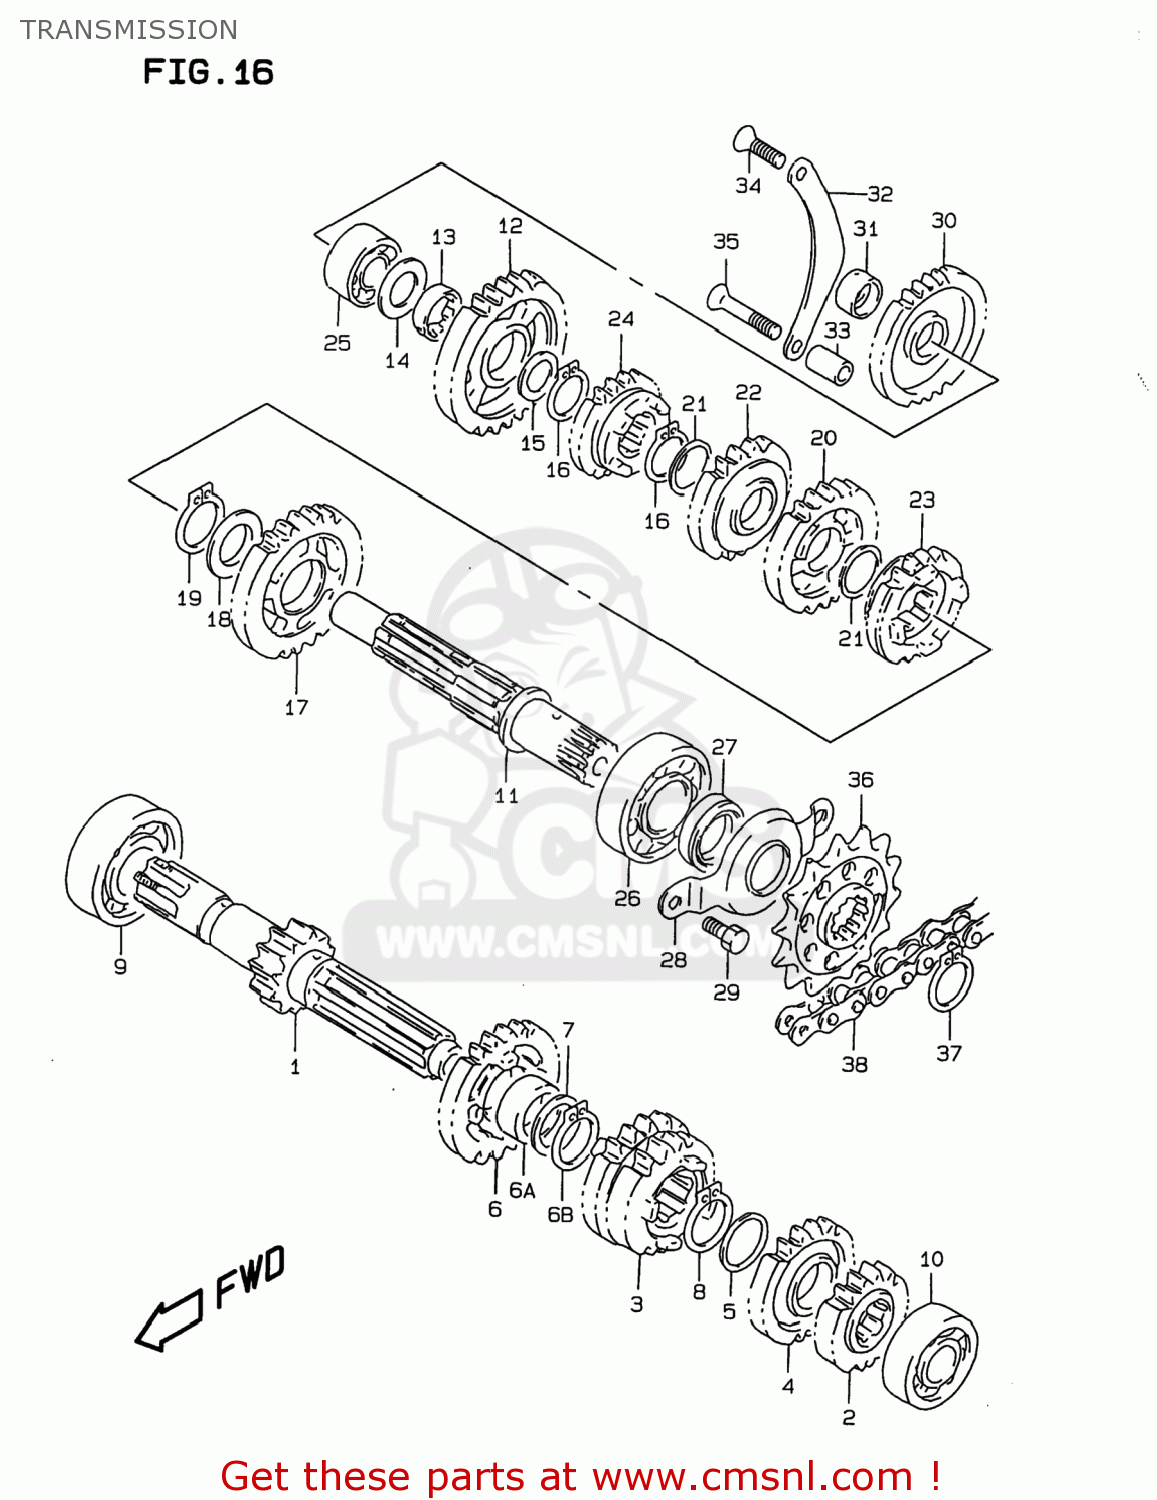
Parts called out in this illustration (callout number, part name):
1	SHAFT,COUNTER(NT:12)
2	GEAR,2ND DRIVE
3	GEAR,3RD & 4TH DRIVE(NT:18/18)
4	GEAR,5TH DRIVE(NT:21)
5	SHIM(22X26X1)
6	GEAR,6TH DRIVE(NT:23)
6A	BUSH(22X26X9)
6B	CIRCLIP
7	SHIM(22X30X1)
8	CIRCLIP
9	BEARING 20X52X15
10	BEARING
11	SHAFT,DRIVE
12	GEAR,1ST DRIVEN(NT:30)
13	BUSH,1ST DRIVEN GEAR
14	WASHER
15	SHIM(22X30X1)
16	CIRCLIP
17	GEAR,2ND DRIVEN(NT:26)
18	SHIM(25X34X1)
19	CIRCLIP
20	GEAR,3RD DRIVEN(NT:24)
21	SHIM(22X28X1)
22	GEAR,4TH DRIVEN(NT:20)
23	GEAR,5TH DRIVEN(NT:20)
24	GEAR,6TH DRIVEN(NT:19)
25	BEARING(17X40X17.5)
26	BEARING(22X56X16)
27	SEAL,OIL(22X34X7)
28	RETAINER,DRIVE SHAFT OIL SEAL
29	BOLT
30	GEAR,KICK STARTER IDLE(NT:27)
31	BUSH,KICK STARTER IDLE GEAR
32	RETAINER,KICK IDLE GEAR
33	SPACER(6.5X12X21)
34	SCREW ,6X16
35	SCREW
36	SPROCKET(NT:15)
37	CIRCLIP
38	CHAIN(DID520VC5,110LE)
